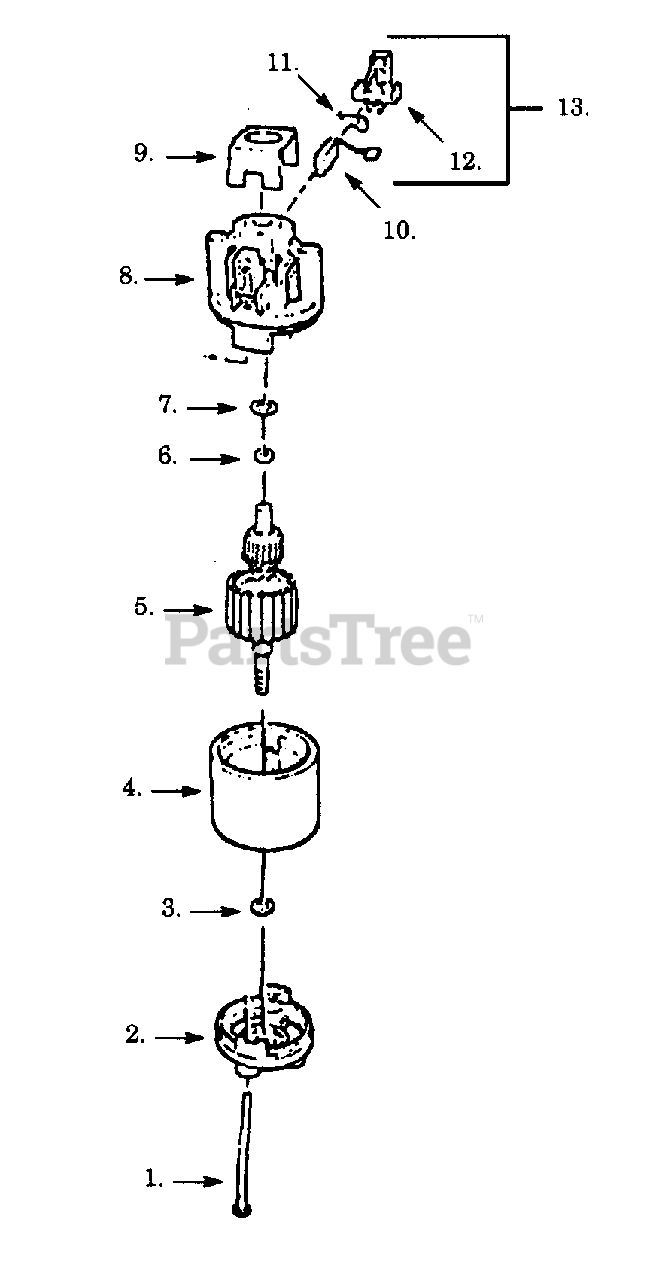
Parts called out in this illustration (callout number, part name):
2	Endbell Ass'y. (Drive)
4	Field Ass'y.
5	Armature Ass'y.
8	Endbell Ass'y. (Brush)
9	Insulator
10	Carbon Brush
11	Brush Spring
12	Brush Holder
13	Brush Kit (Incl. 10,11,12)
